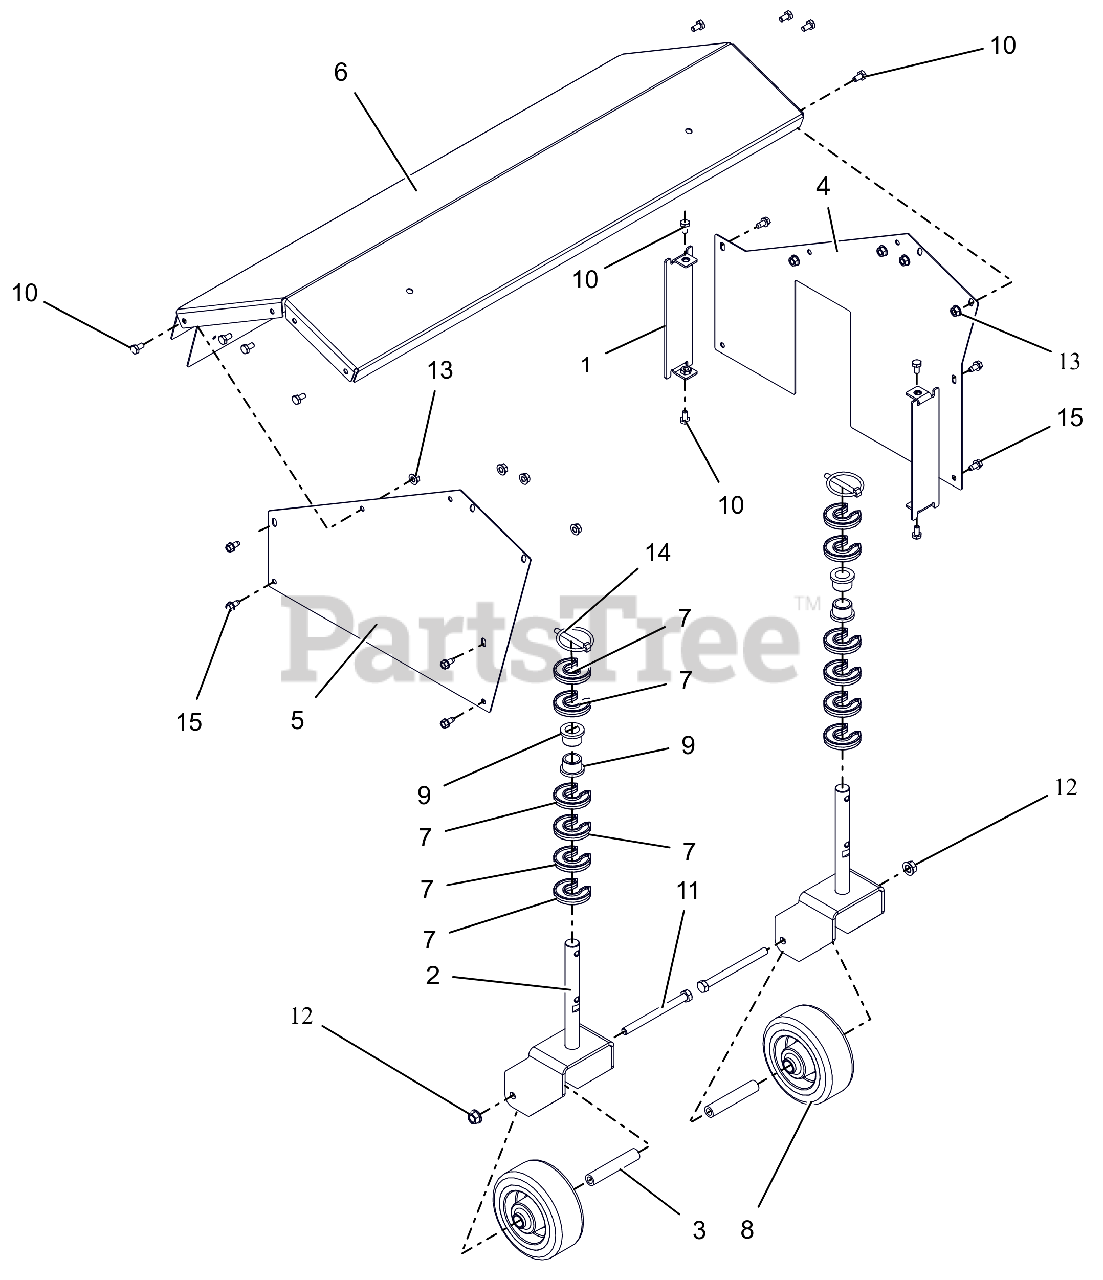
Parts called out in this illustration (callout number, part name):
1	COVER,END
2	FORK, CASTER-BRUSH
3	SPACER, CASTER WHEEL
4	COVER,LH SIDE BRUSH
5	COVER,RH SIDE BRUSH
6	COVER WITH DECALS, 28"BRUSH
7	CLIP-HOC FIXED
8	WHEEL, CASTER - 5"OD
9	BUSHING, FLANGE .75X.75X1.0
10	@BLT-HEX .25-20X.50 GR5 YWZC
11	@BLT-HEX .38-16X4.50 GR5 YWZC
12	@NUT-LK-TOP-FLG .38-16 YWZC
13	@NUT-LK-TOP-FLG .25-20 YWZC
14	PIN, LYNCH - .25 X 1.25
15	SCR-TAP .25-20X.50 HWH TR YWZ
